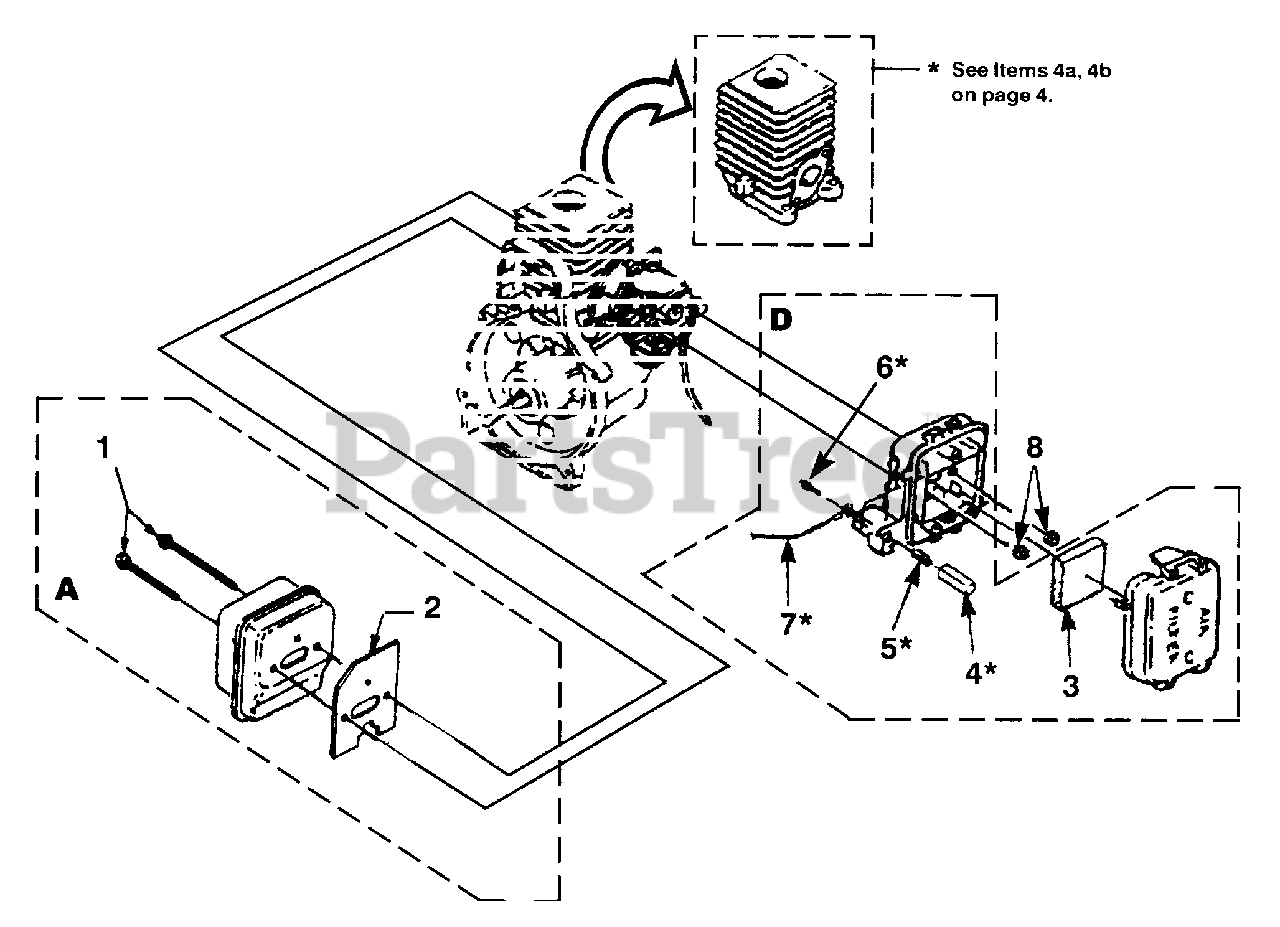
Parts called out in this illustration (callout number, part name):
1	SCREW - Sems Hex (10-24 X 2-1/2")
2	GASKET - Muffler
3	FILTER - AIR
4	BUTTON - Switch
5	SPRING - Compression
6	SCREW - Plastite (#6)
7	LEAD - Electrical
8	NUT - Hex (10-24)
A	MUFFLER COMPLETE
D	AIR FILTER KIT
